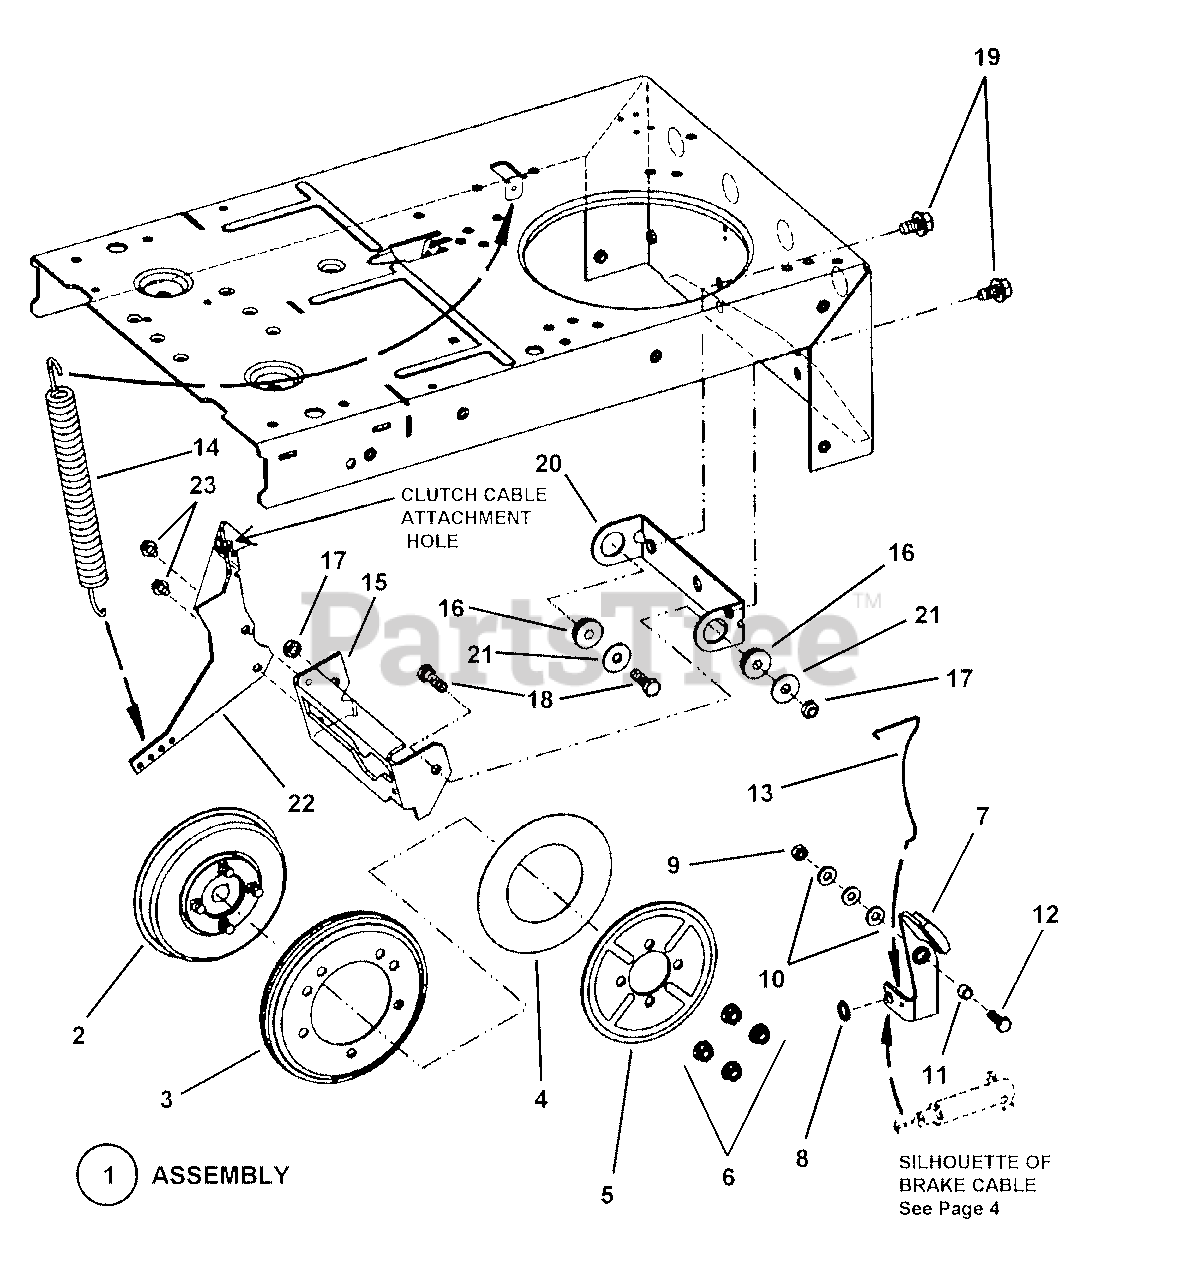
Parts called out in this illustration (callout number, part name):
1	ASSEMBLY, Smooth Clutch
2	ASSEMBLY, Driven Disc Hub
3	DISC, Driven
4	WASHER, Thrust
5	PLATE
6	NUT, 5/16-18 Hex Flange Lock
7	ASSEMBLY, Brake Lever
8	RING, 3/8" External Retaining
9	NUT, 1/4-28 Hex Top Lock
10	WASHER, 1/4 Flat
11	SPACER
12	SCREW, 1/4-28 x 1" Hex Head Cap Grade 5
13	SPRING, Brake Return
14	SPRING, Clutch Brake
15	LIFT, Yoke
16	BEARING, Yoke
17	NUT, 5/16-24 Hex Center Lock
18	SCREW, 5/16-24 x 1" Hex Head Cap, Grade 5
19	SCREW, 3/8-16 x 5/8" Hex Washer Self-Tap
20	COLLAR, Yoke
21	WASHER, 5/16 Flat
22	ARM, Yoke
23	SCREW, 1/4-20 x 3/8" Hex Washer Self-Tap
